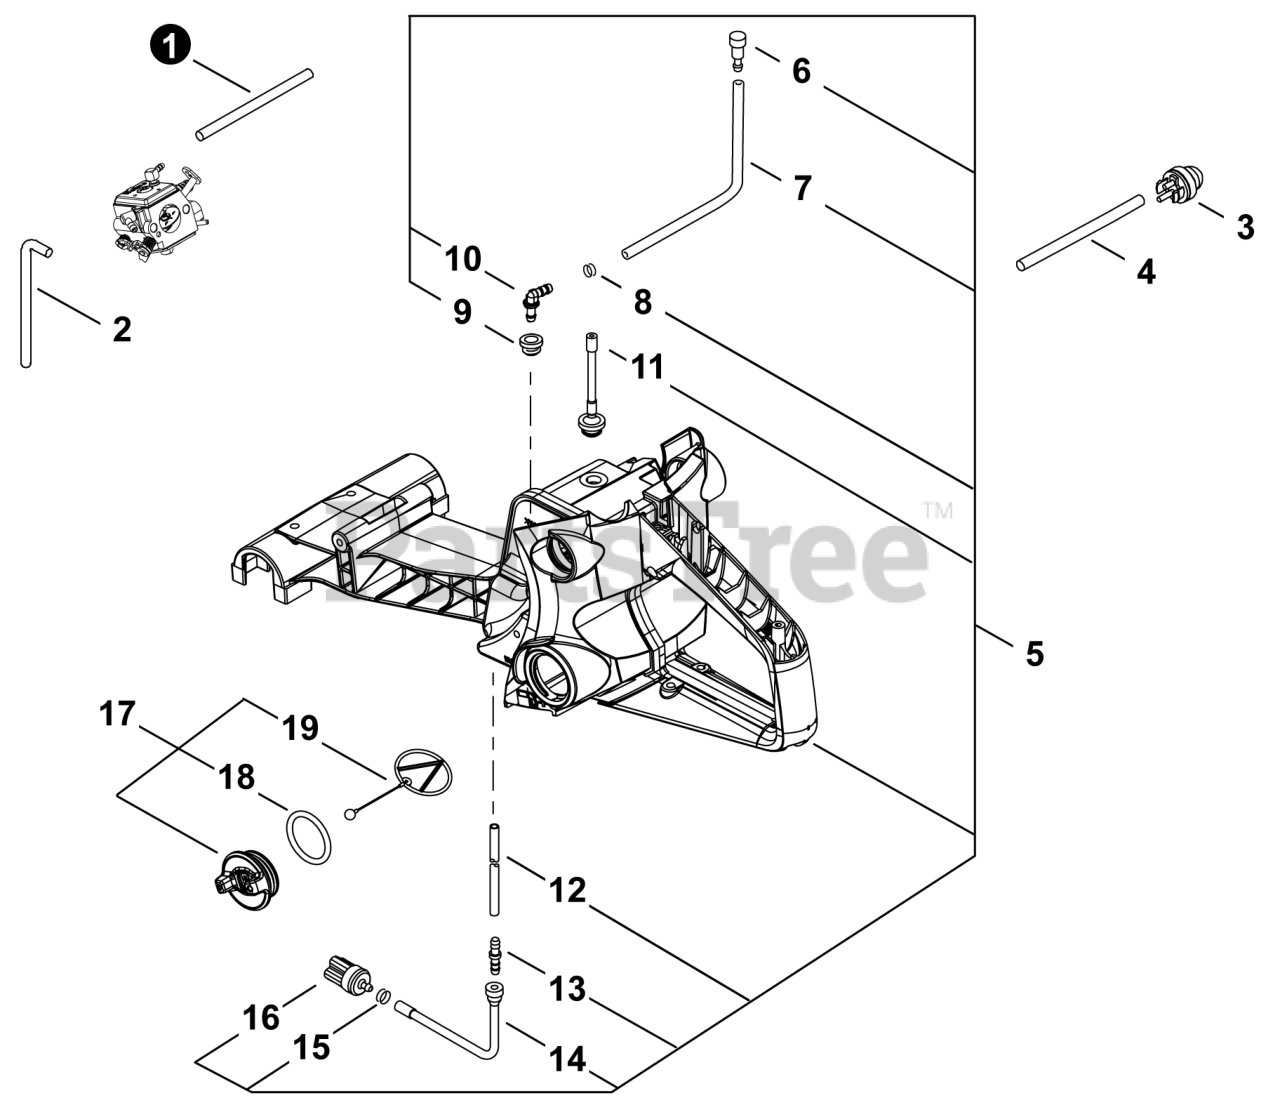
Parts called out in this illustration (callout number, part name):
1	PIPE, PULSE 3x6x135
2	PIPE, PULSE 3x6x110
3	BULB, PURGE
4	PIPE, FUEL
5	HANDLE ASSY, REAR
6	VENT ASSY
7	PIPE, FUEL 3x5x255
8	CLIP
9	GROMMET, FUEL
10	CONNECTOR, PIPE
11	PIPE
12	PIPE, FUEL 3x6x75
13	CONNECTOR, PIPE
14	PIPE, FUEL
15	CLIP 6
16	FILTER, FUEL
17	CAP ASSY, FUEL
18	O-RING 29
19	CONNECTOR, CAP L= 60 MM
